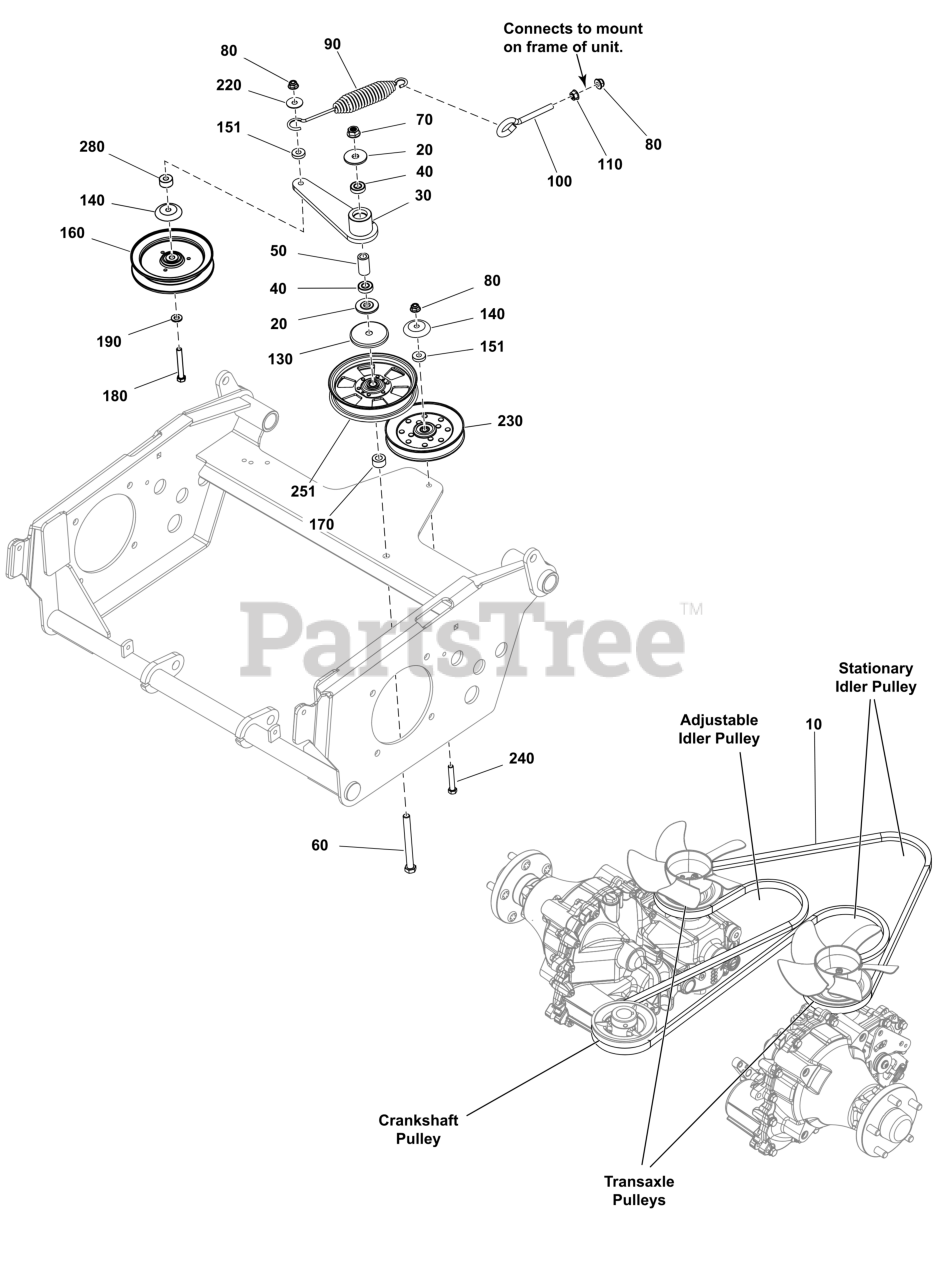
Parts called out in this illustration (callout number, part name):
10	BELT, DRIVE
20	SPACER, IDLER ARM
30	ARM, IDLER
40	BEARING, BALL, AXLE
50	SPACER, .52 X .84 X 1
60	BOLT, 1/2-13 X 5" GD5
80	NUT, 3/8-16 HEX NYLOCK
90	SPRING, EXTENSION
100	EYEBOLT - 3/8-16
110	NUT, 3/8-16 HEX SERRA
140	SHIELD, BRNG PULLEY
151	SPACER, .39 X 1.00 X
160	PULLEY, C-SEC,V-IDLER
180	BOLT, 3/8-16 X 2-3/4"
190	WASHER, 3/8"
220	WASHER, 3/8" FENDER
230	PULLEY-IDLER-V
240	BOLT, 3/8-16 X 2-1/4"
